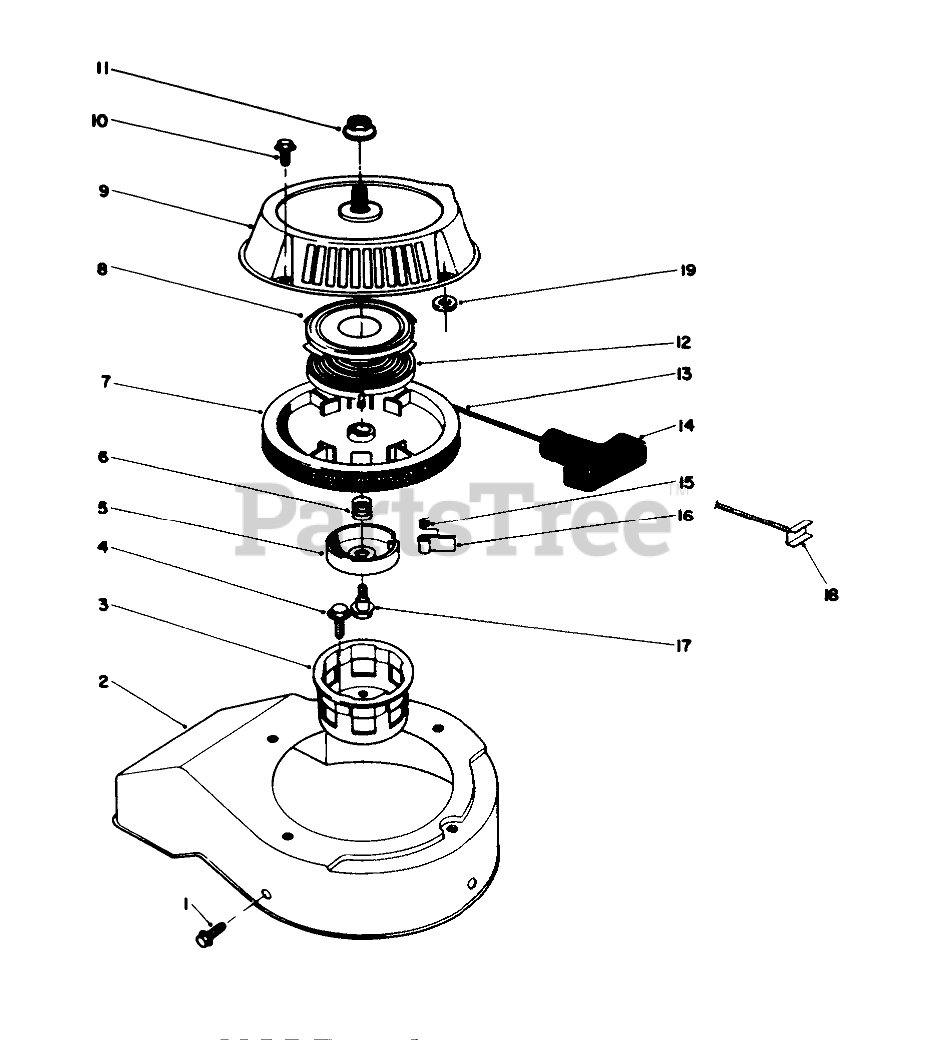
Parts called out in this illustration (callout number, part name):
2	BLOWER SHROUD
3	CUP - STARTER
4	WASHER-FLAT HD, TREATED
5	RETAINER
6	SPRING
8	Retainer-Recoil Spring
9	RECOIL CASE
10	MOUNTING SCREW
11	NUT (F/W & PPP)
12	Spring-Recoil
13	ROPE-STARTER
14	HANDLE-RECOIL
15	SPRING
18	Insert Handle
19	SPACER-PLATE, PIVOT
